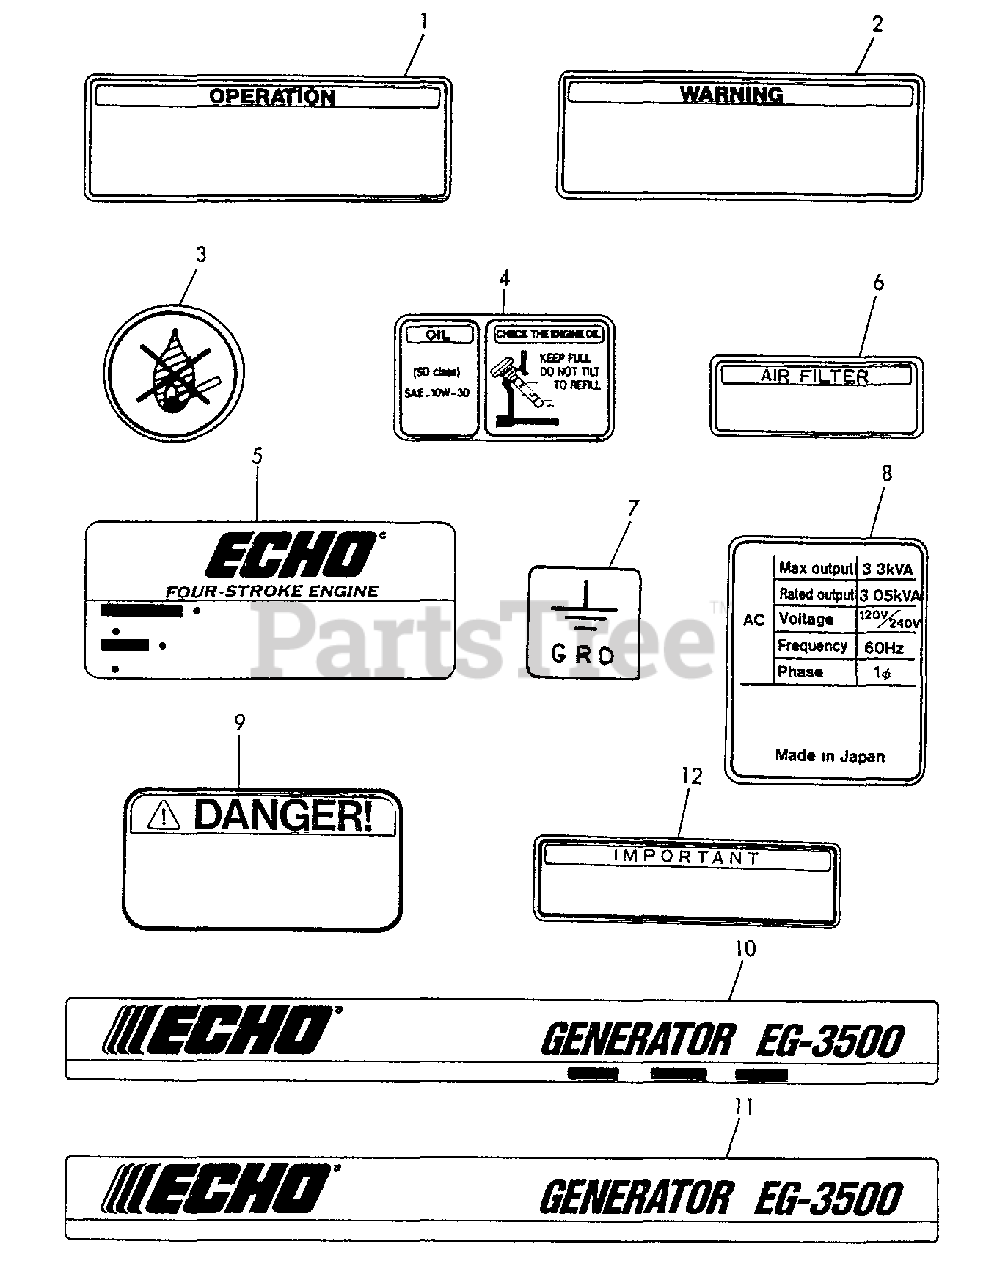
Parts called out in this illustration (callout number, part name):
1	LABEL
2	LABEL - WARNING
3	LABEL, NON FIRE
4	LABEL, OIL
5	LABEL, ECHO
6	LABEL - AIR FILTER
7	LABEL, EARTH
8	LABEL - GENERATOR
9	LABEL DANGER
10	LABEL - GENERATOR
11	LABEL - GENERATOR
12	LABEL - IMPORTANT
